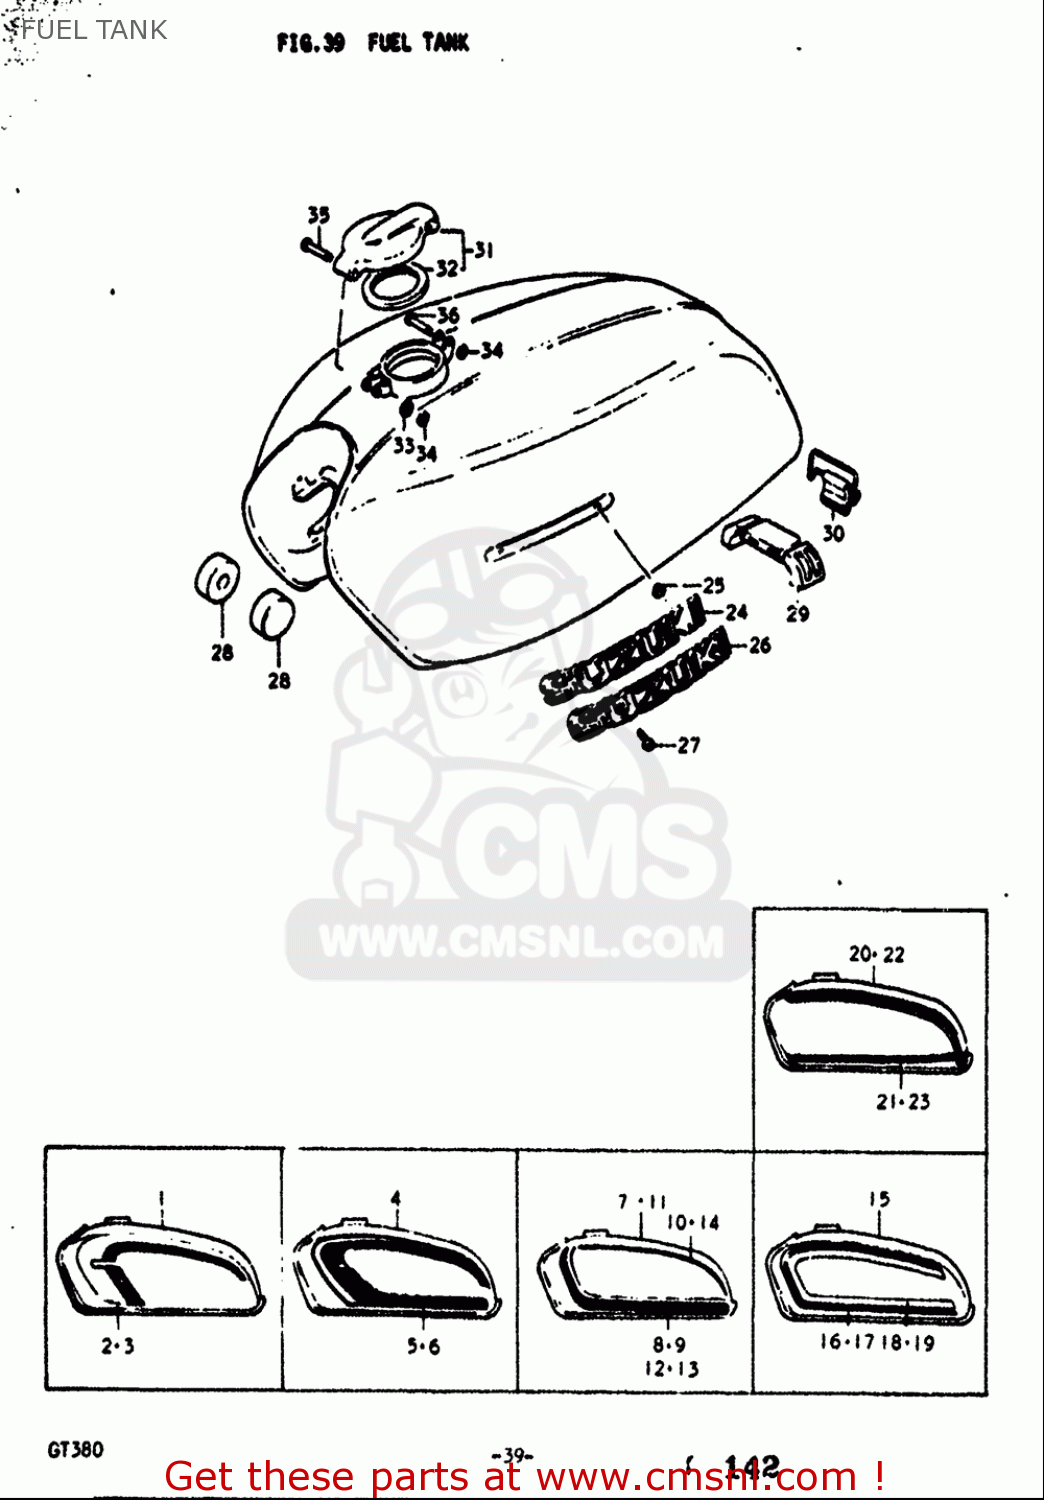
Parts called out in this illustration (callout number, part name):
25	NUT
26	EMBLEM,FUEL TANK
27	SCREW
28	CUSHION
29	CUSHION
30	BAND
31	CAP ASSY,FUEL TANK
32	GASKET (NAS)
33	WASHER
34	E RING
